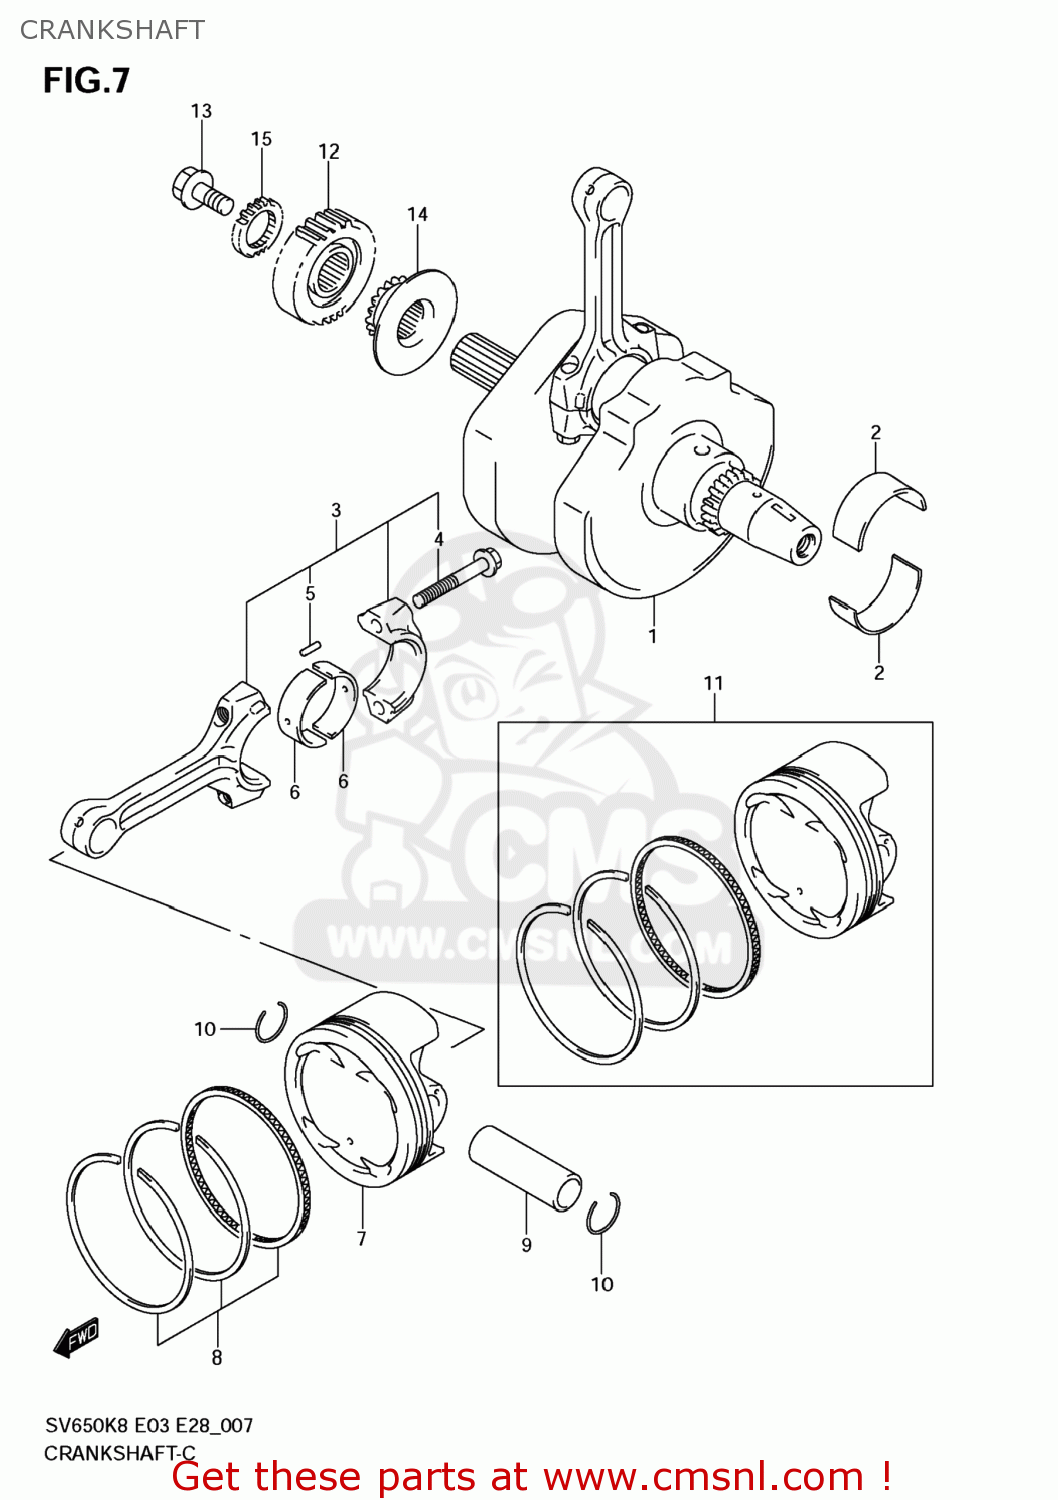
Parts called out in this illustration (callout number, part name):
1	CRANKSHAFT
2	BEARING,CRANKSHAFT(GREEN)
3	CONNECTING ROD ASSY
4	BOLT,CONNECTING ROD
5	PIN,CONNECTING ROD
6	BEARING,CRANK PIN
7	PISTON
8	RING SET,PISTON
9	PIN,PISTON
10	CIRCLIP,PISTON PIN
11	PISTON SET(OS:0.5)
12	GEAR,PRIMARY DRIVE
13	BOLT(10X19)
14	SPROCKET,CAM CHAIN DRIVE
15	GEAR,WATER PUMP DRIVE
